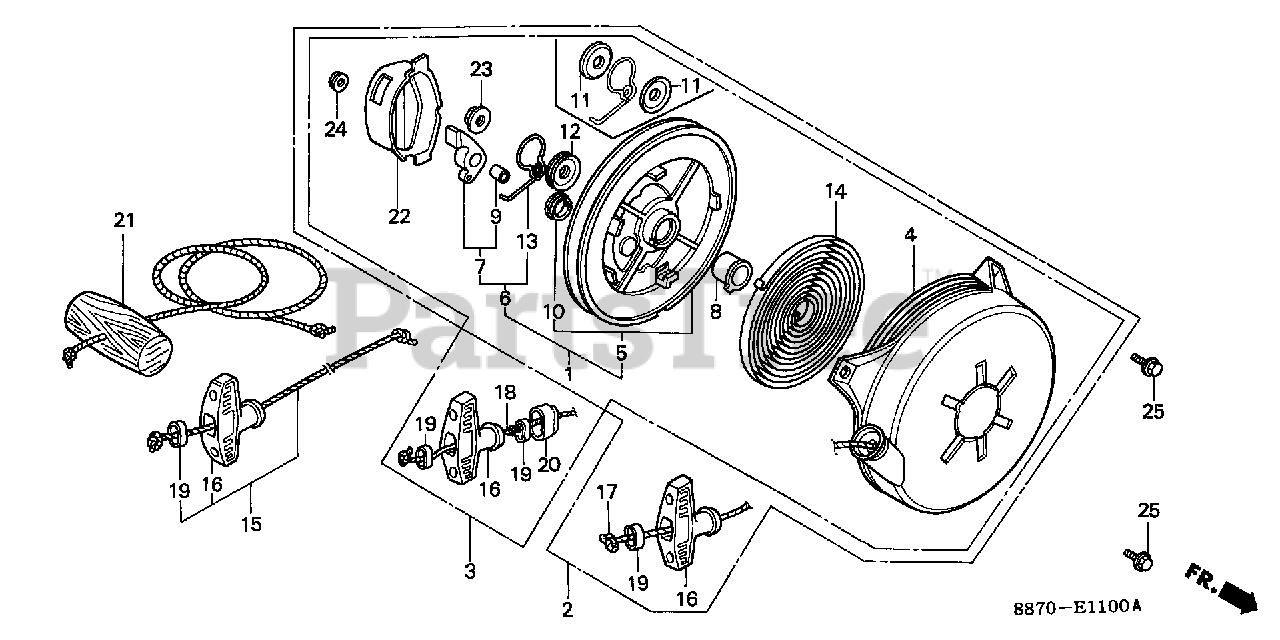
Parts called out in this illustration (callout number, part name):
1	REEL KIT, STARTER Use up to Engine SN 1364584.
2	STARTER ASSY., RECOIL *R8* (BRIGHT RED)
4	CASE, STARTER *R8* (BRIGHT RED)
5	REEL KIT, STARTER
5	REEL, STARTER
6	RATCHET KIT Use up to Engine SN 1072857.
6	RATCHET KIT Use up to Engine SN 1364584.
7	RATCHET KIT
7	RATCHET
8	BOSS, REEL
9	BUSH, RATCHET
10	BUSH, REEL STARTER
11	PLATE, FRICTION
12	PLATE, FRICTION
13	RATCHET KIT
13	SPRING, FRICTION
14	SPRING, RETURN
16	GRIP, STARTER
17	ROPE, STARTER
19	SUPPORT, GRIP
21	ROPE, STARTER
22	COVER, STARTER REEL
23	NUT, SELF-LOCK (8MM)
24	NUT, FLANGE (5MM)
25	BOLT, FLANGE (6X8)
